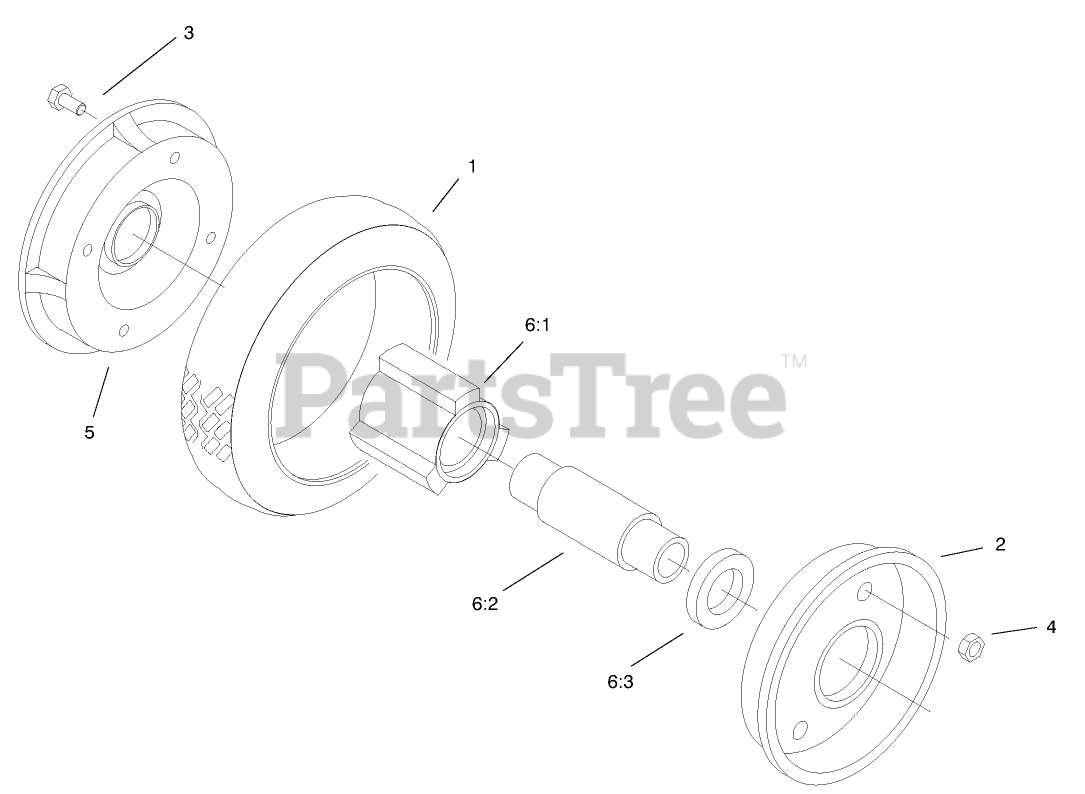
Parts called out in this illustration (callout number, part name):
3	SCREW-HH
4	NUT-LOCK, NI
6	Loose Parts Package
6:1	HUB-BEARING
6:2	SPACER-BEARING
6:3	BEARING-WHEEL
